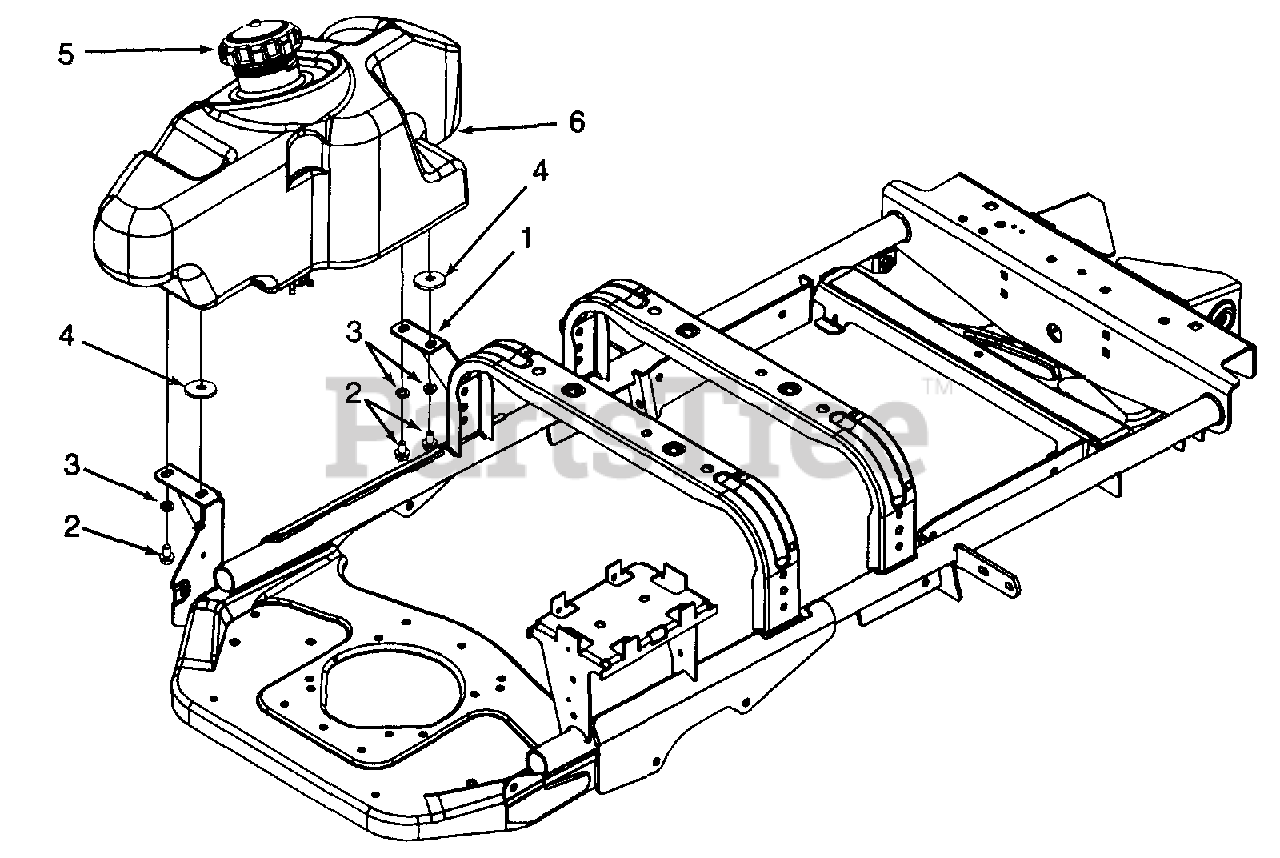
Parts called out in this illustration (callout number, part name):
3	Washer, Lock, 3/8
4	Washer, Flat, .390 x 3.5 x .10
5	Cap, Fuel
6	Fuel Tank
